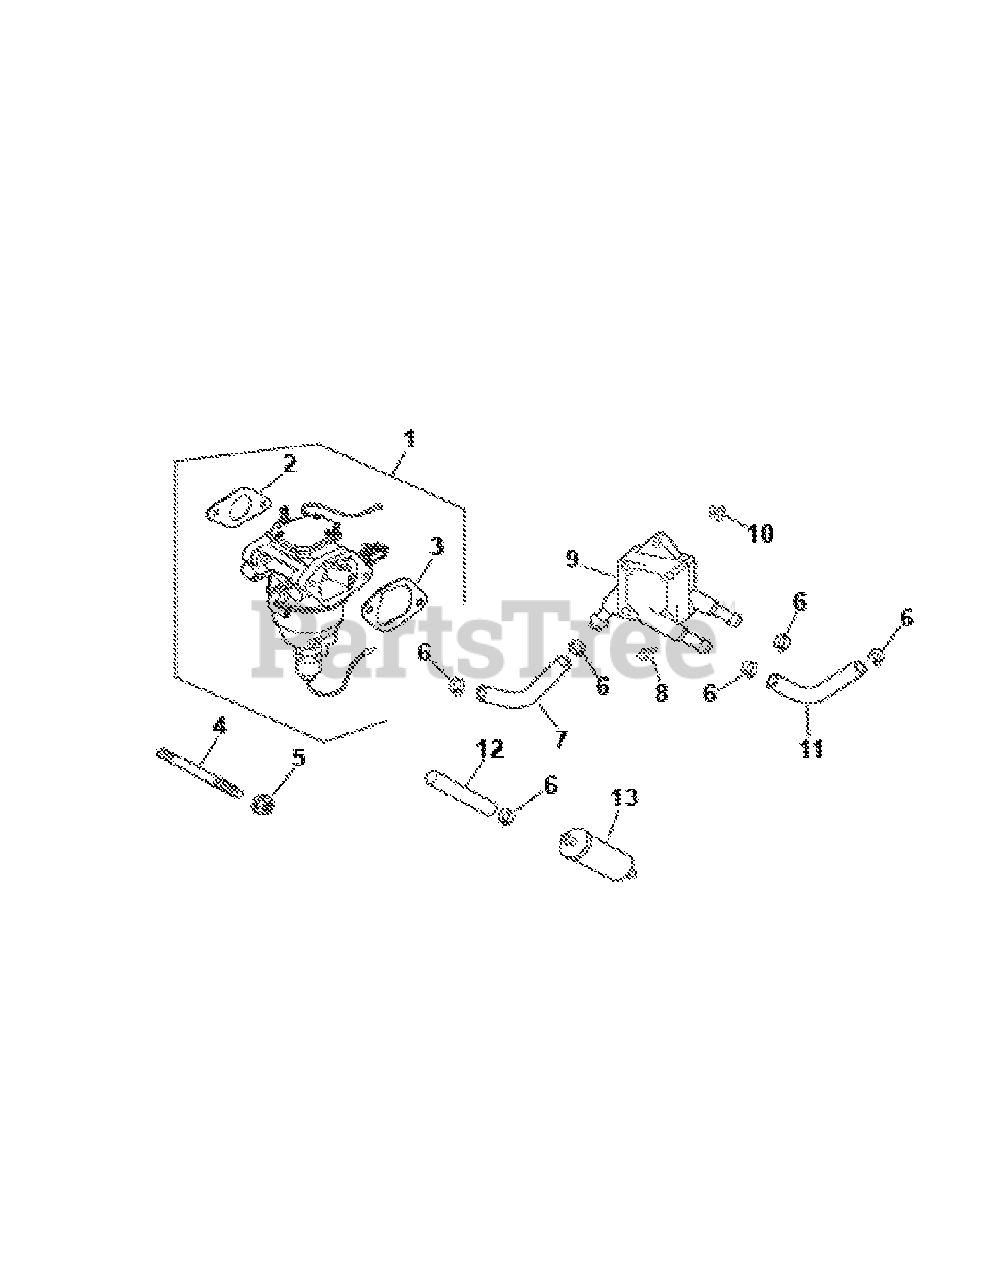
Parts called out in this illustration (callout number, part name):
1	Carburetor w/Gaskets
2	Carburetor Gasket
3	Air Cleaner Base Gasket
4	Intake Manifold Stud
7	Fuel line 12.5"
11	Fuel Line 11"
12	Fuel Line 3.5"
13	Fuel Filter
